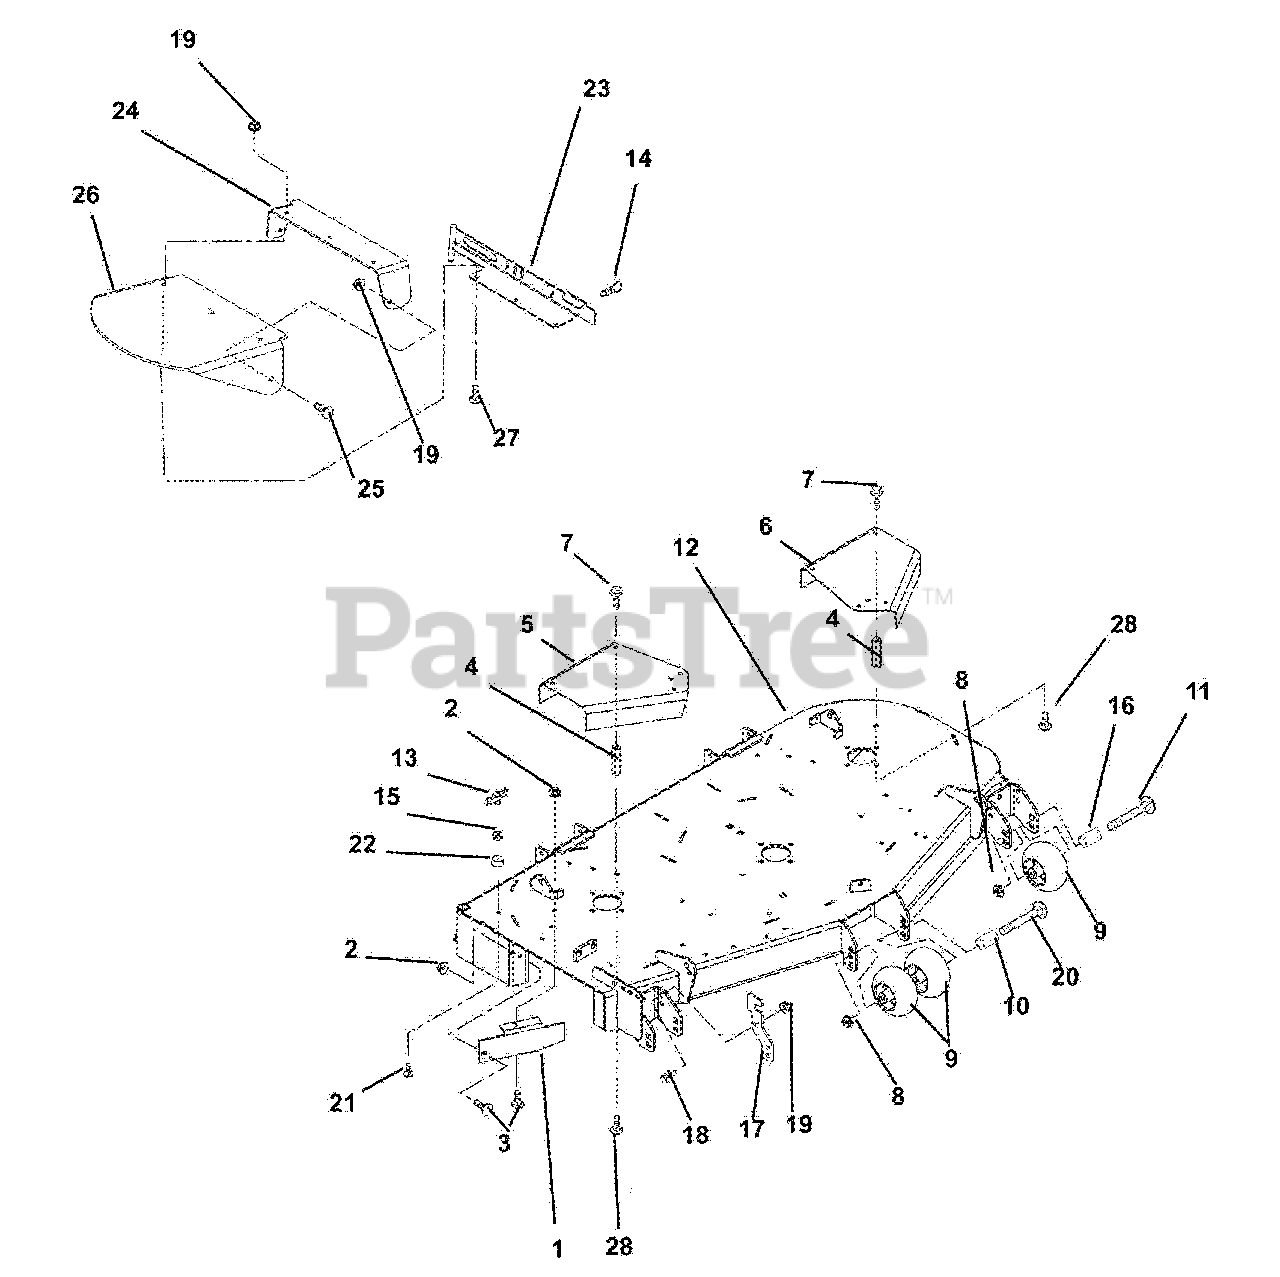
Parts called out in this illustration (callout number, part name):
1	60-in. Discharge Baffle (992156)
2	Nut, .31-18 Nyloc Flange
3	Bolt, Round Head Square Neck .31-18 x 1.00 Grade 5
4	Coupling Nut, .31-18 x 3.00
5	60-in. Right Hand Spindle Guard (992156)
6	60-in. Left Hand Spindle Guard (992156)
7	Bolt, SEMS .31-18 x .62
8	Nut .50-13 Nyloc Flange
9	Anti-Scalp Wheel
11	Bolt-Round Head Square Neck .50-13 x 5.00
12	60-in. Mower Deck (992156)
13	Knob, Wing .312-18
14	Pin, Pull Plunger .50-13 Thread x .310
15	Nut, Locking Center .31-18
16	Spacer, .510 x .625 x 3.35
17	Chute, Storage Bracket
18	Bolt, Hex .38-16 x 1.00
19	Nut, .38-16 Nyloc Flange
20	Bolt, Round Head Square Neck .50-13 x 8.50
21	Bolt, Round Head Square Neck .31-18 x 1.50
22	Bumper, Recessed 1.50 x .63 , .31 Thru Hole
23	60-inch Discharge Chute Mounting Weldment (992156)
24	Rubber Discharge Chute Support
25	Bolt, Round Head Square Neck .38-16 x 1.00 Grade 5
26	Chute, Rubber Discharge
27	Bolt, Round Head Square Neck .38-16 x 1.25 Grade 5
28	Bolt, Round Head Square Neck .31-18 x .75 Loc-Tite
